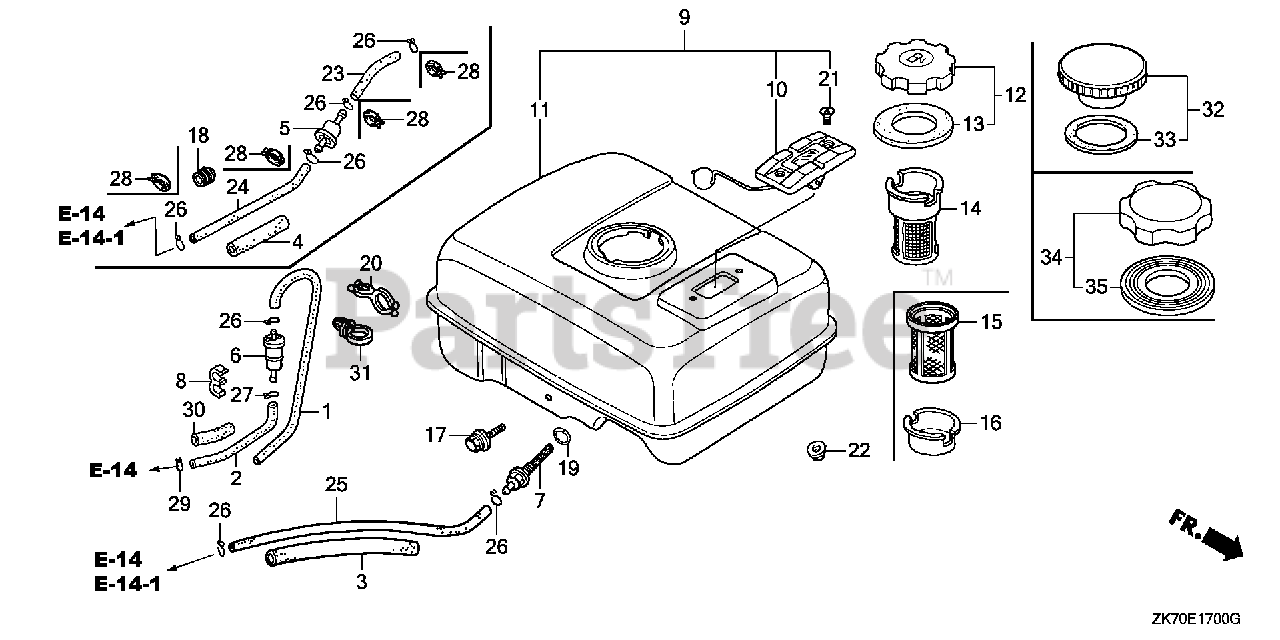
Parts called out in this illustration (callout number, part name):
3	RUBBER, SUPPORTER (107MM)
7	JOINT, FUEL TANK
11	TANK, FUEL *NH31* (MCKINLEY WHITE)
11	TANK, FUEL *NH1* (BLACK)
17	BOLT, FLANGE (6X29)
19	O-RING (13.5X1.5) (ARAI)
19	O-RING (14MM) (NOK)
22	NUT, FLANGE (6MM)
25	BULK HOSE, FUEL (4.5X3000) (4.5X140)
26	CLIP, TUBE (B8)
34	CAP, FUEL FILLER (CHROME PLATED) (TOYOSHA)
35	GASKET, FUEL FILLER CAP (39X62X3) (TOUYOUSYA)
